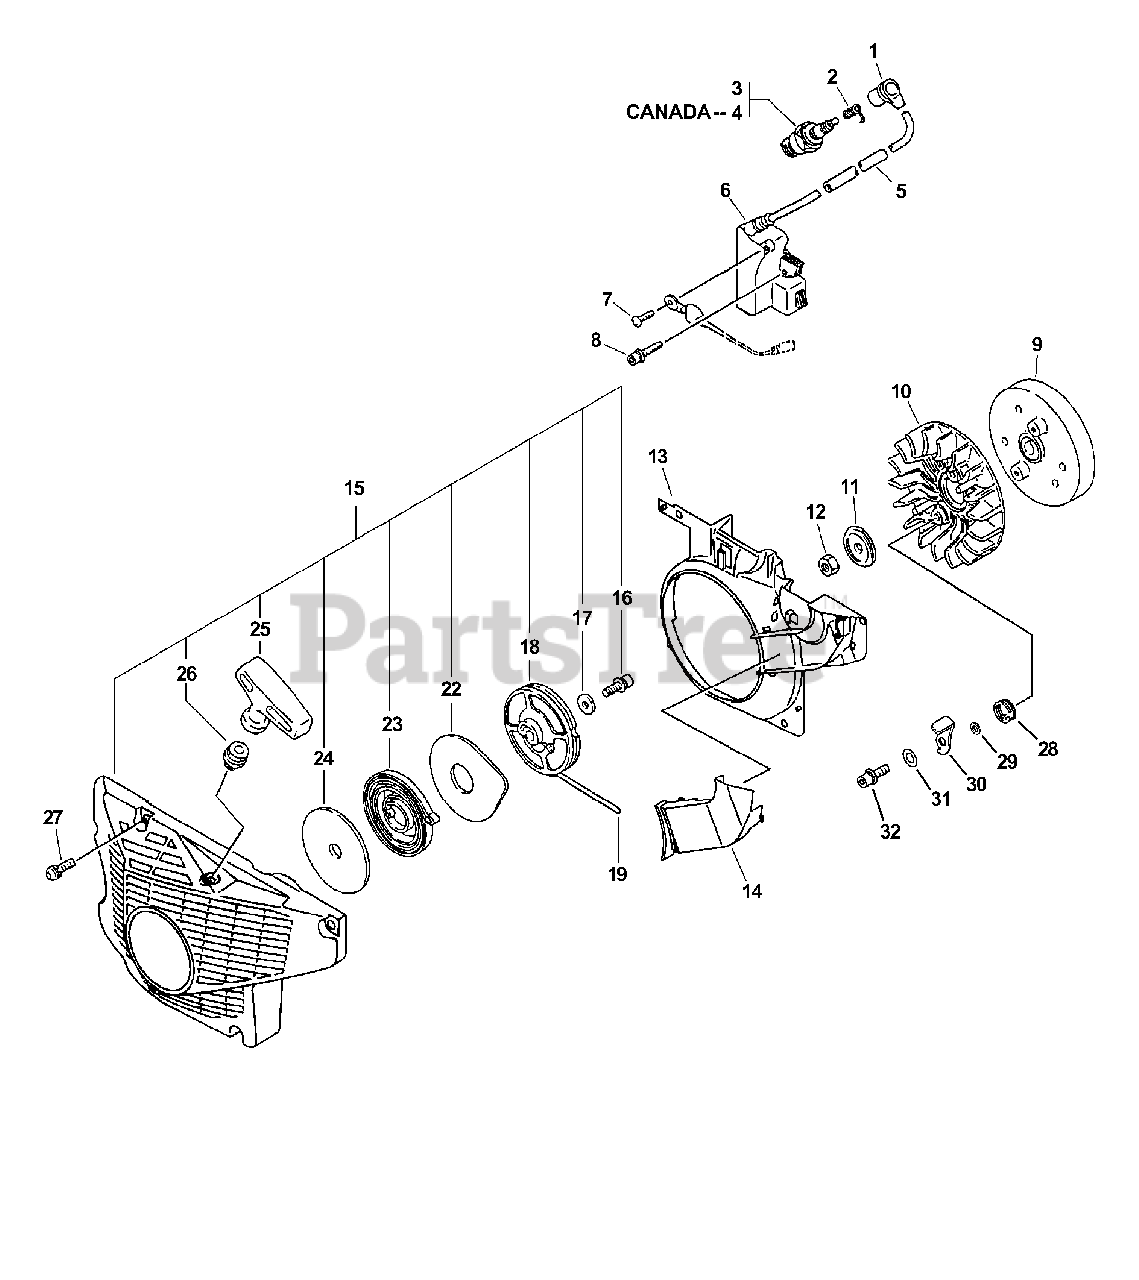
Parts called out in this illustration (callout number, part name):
1	CAP, SPARK PLUG
2	TERMINAL, SPARK PLUG CAP
3	SPARK PLUG -- BPM-7A
4	SPARK PLUG -- BPMR-7A
6	COIL, IGNITION
7	SCREW - 4X8
8	SCREW - 4X20
9	FLYWHEEL
11	WASHER - CUP
13	COVER, FAN
14	DUCT, AIR
15	STARTER ASSY
16	SCREW - 5X14
17	WASHER - 5
18	REEL, ROPE
19	ROPE, STARTER - 4X950
20	SCREW - 4X8
21	RETAINER, BRAKE BAND
22	PLATE, STARTER
23	SPRING, REWIND
24	PLATE, STARTER
25	GRIP, STARTER
26	GUIDE, ROPE
27	SCREW - 5X20
28	SPRING, RETURN
29	SPACER, PAWL
30	PAWL, STARTER
31	WASHER - 5
32	SCREW - 5X20
